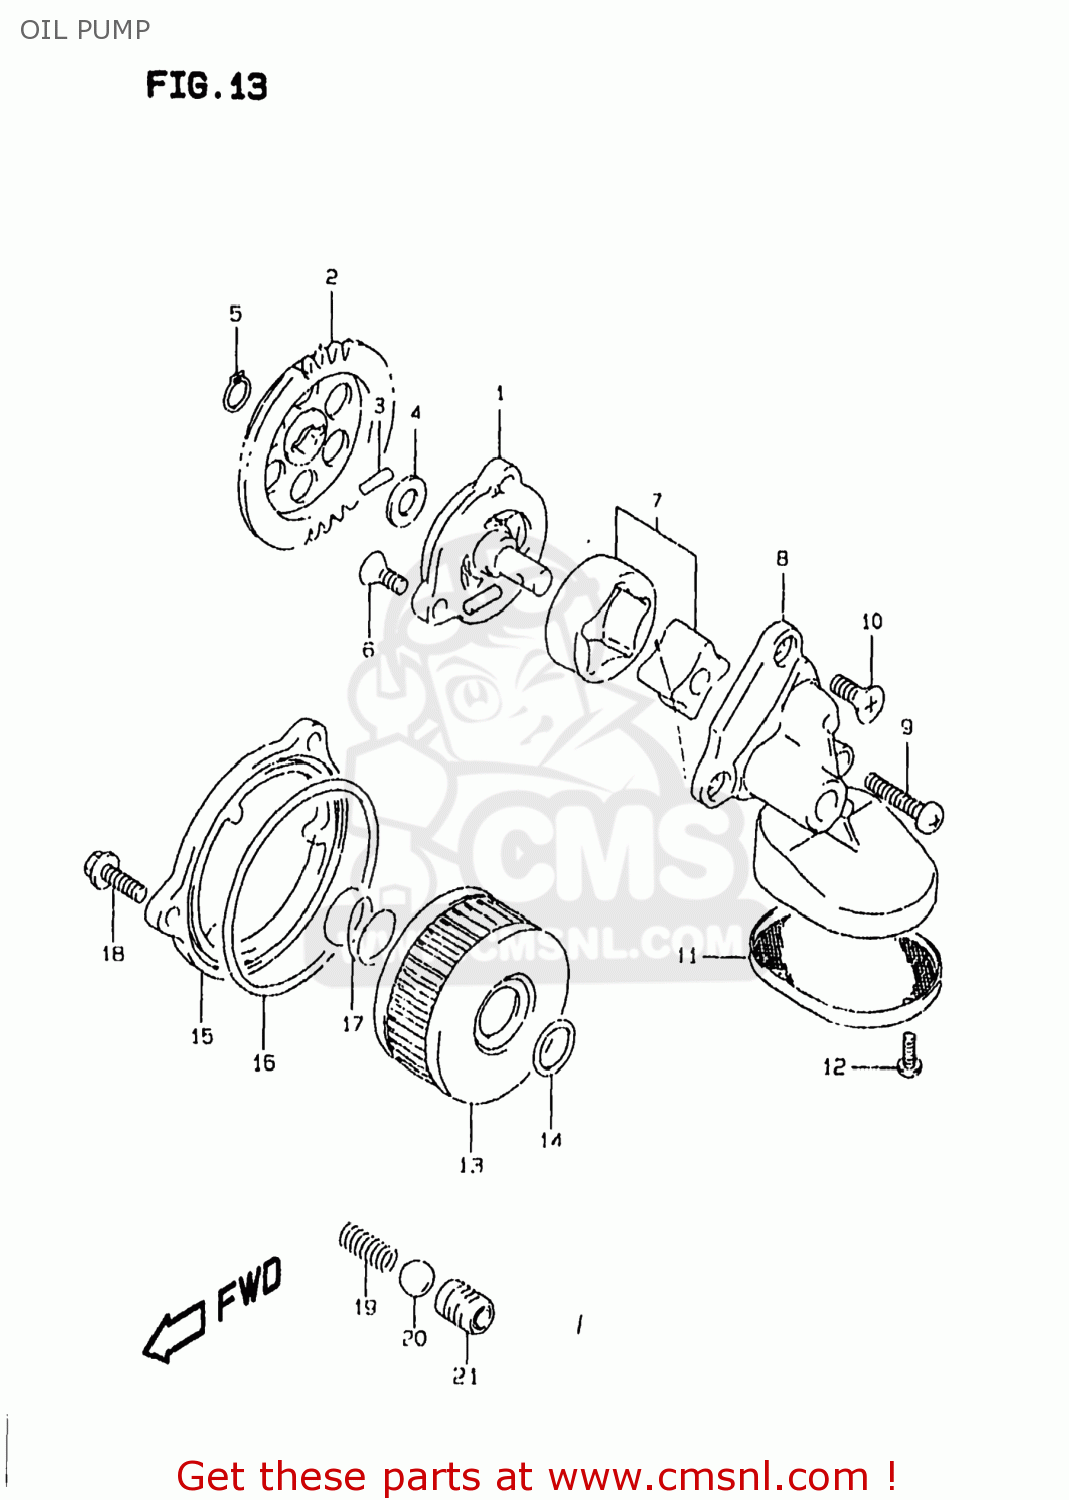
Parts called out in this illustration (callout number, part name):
1	PUMP ASSY,ENGINE OIL NO.1
2	GEAR,OIL PUMP DRIVEN (N
3	PIN(4X15.8)
4	SHIM(10X18X0.5)
5	CIRCLIP,10MM
6	SCREW ,6X16
7	ROTOR SET,OIL PUMP,NO.2
8	COVER,OIL PUMP NO.2
9	SCREW 6X30
10	SCREW ,6X16
11	STRAINER,OIL PUMP NO.2
12	SCREW
13	FILTER ASSY,ENGINE OIL
14	O RING(D:2.4,ID:15.8)
15	CAP,OIL FILTER
16	O RING(D:2.4,ID:73)
17	SPRING
18	SCREW
19	SPRING
20	BALL
21	SEAT,OIL CHECK VALVE
